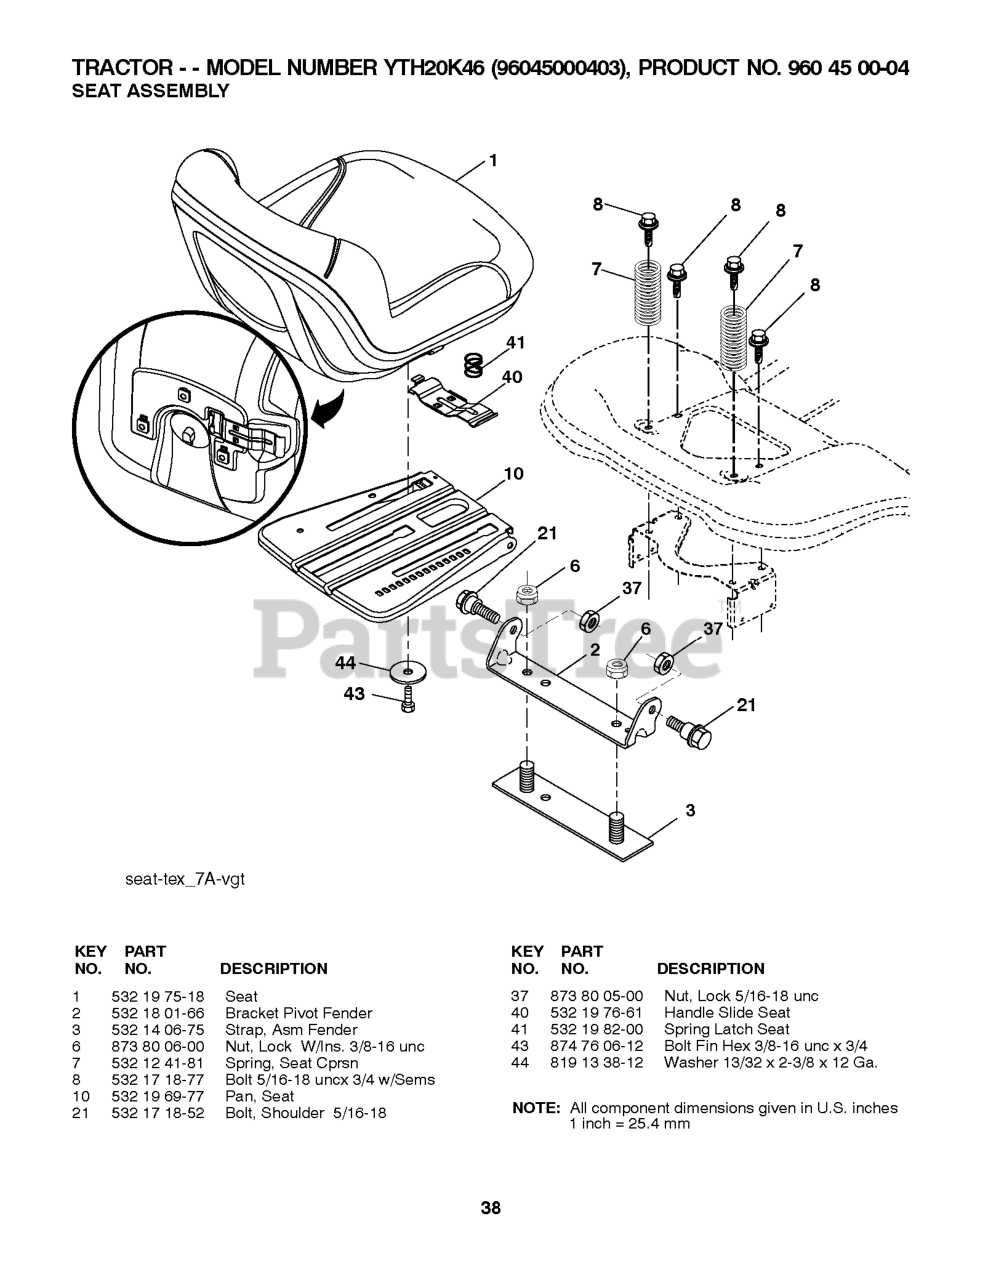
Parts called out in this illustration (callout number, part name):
1	SEAT.TH130.GRY.MILSCO.
2	BRKT.PIVOT.FENDER
3	STRAP
6	NUT
7	SPRING COMPRESSION
8	BOLT.5/16-18UNCX3/4 W/SEMS.BLK
10	PAN.ASM.SEAT.3PT
21	BOLT.SHOULDER.5/16-18
37	NUT.71038.31-18.HEX.NYLOCK
40	HANDLE.SLIDE.SEAT.TEX.BLACK
41	SPRING.LATCH.SEAT.TEX
44	WASHER 13/32 X 2-3/8 X 12GA
